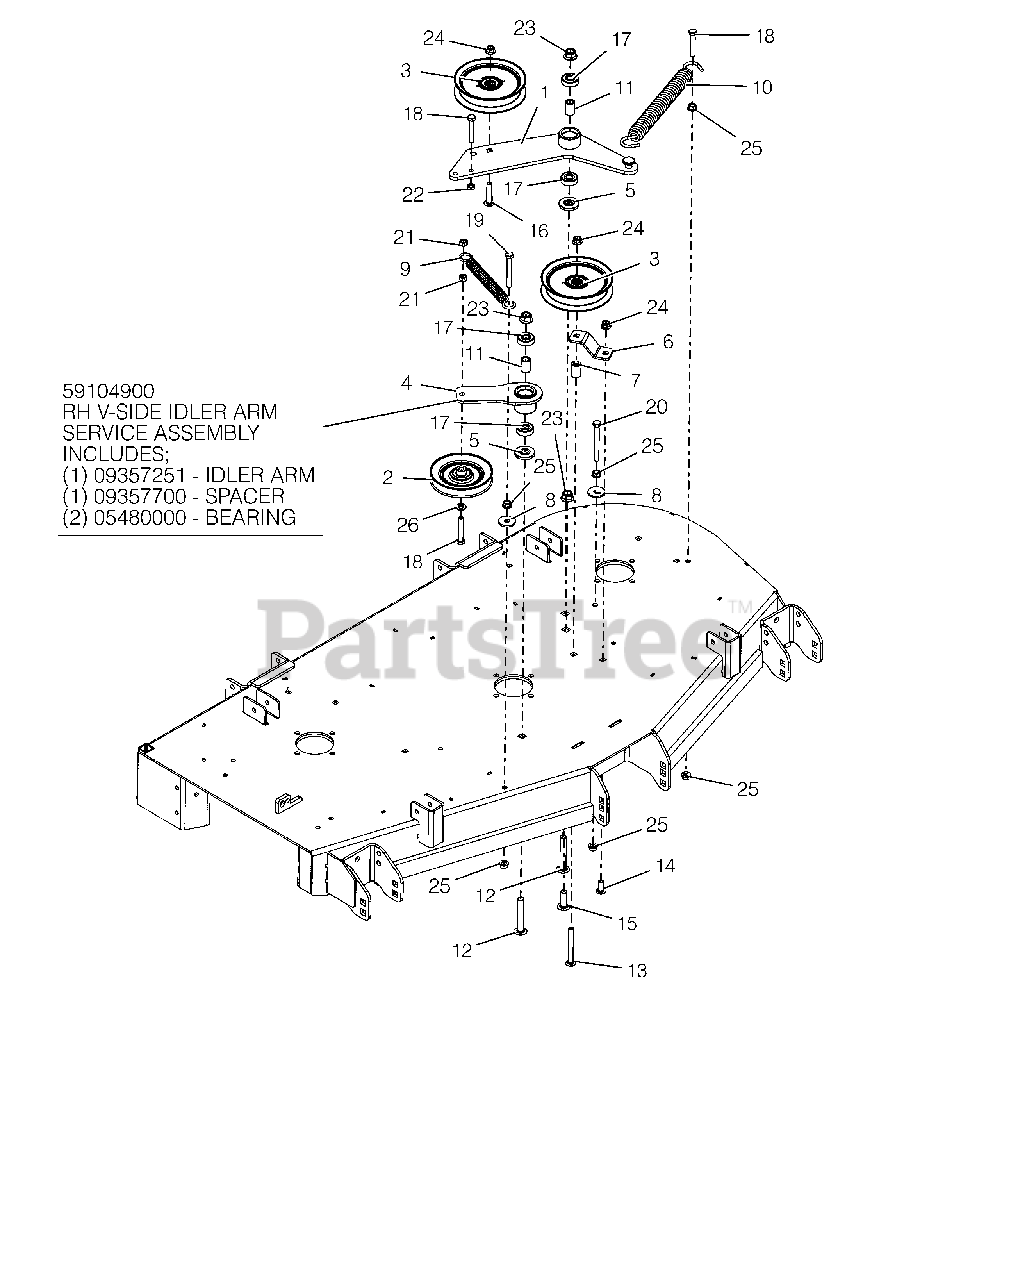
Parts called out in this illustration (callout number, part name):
1	DECK PTO IDLER ARM WLDMT - BLK
2	IDLER, V-5.00"
3	IDLER, FLAT 5.00"
4	DECK RH IDLER ARM WMT - BLK
4	RH V-SIDE IDLER ARM ASSEMBLY
4	SPACER .510 X .75 X 1.1485
4	BRG-BALL .50X1.38X.438 SEALED
5	SPACER, IDLER ARM
6	PTO FIXED IDLER MTG BRKT -RED
7	BUSHING, SLV .380X.750X1.190
8	WSHR-FL-STL .406X1.375X.135 YZ
9	SPRING, EXTENSION
10	SPRING, EXTENSION
11	SPACER .510 X .75 X 1.1485
12	BLT,RDHDSQSHNK.50-13X3.25 G5YZ
13	@BLT-RHDSSQNK .38-16X3.50 G5YZ
14	@BLT-RDHDSHSQNK.38-16X1.0 G5YZ
15	BLT-RDHDSHSQNKFT.50-13X1.50 G5
16	BLT-RDHDSQNK .38-16X2.00 SHTYW
17	BRG-BALL .500X1.38X.437
18	@BLT-HEX .38-16X2.25 GR5 YWZC
19	@BLT-HEX .38-16X3.00 GR5 YWZC
20	@BLT-HEX .38-16X3.50 GR5 YWZC
21	@NUT-LK-CTR .38-16 YWZC
22	NUT-HEX-JAM .375-16 YWZC
23	@NUT-LK-NYL-FLG .50-13 YWZC
24	@NUT-LK-NYL-FLG .38-16 YWZC
25	@NUT-SPNLK-FLG .375-16 YWZC
26	@WSHR-FL-STL.406X.812X.065 YWZ
